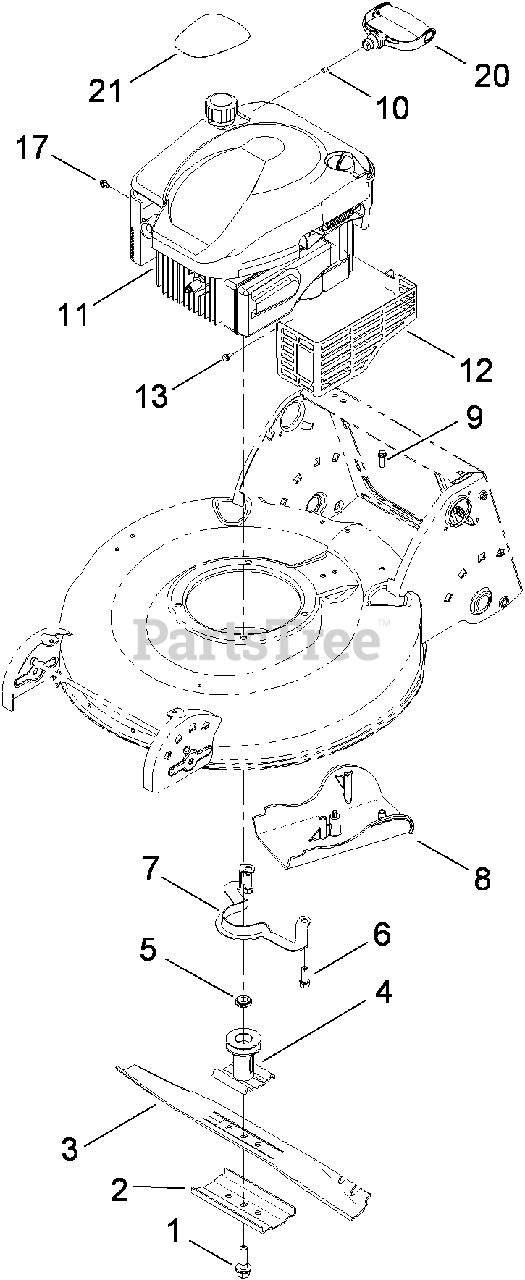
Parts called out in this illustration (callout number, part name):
1	BOLT-BLADE
2	SUPPORT-BLADE
3	BLADE-21 INCH
4	BLADE DRIVER ASM
5	Spacer-Driver
6	SCREW-HWH
8	COVER-BELT
9	SCREW-HWH
10	STOP-ROPE
12	SHIELD-MUFFLER
13	SCREW-TAPTITE
17	SCREW-HWH
20	HANDLE-RECOIL
21	DECAL-ENGINE
